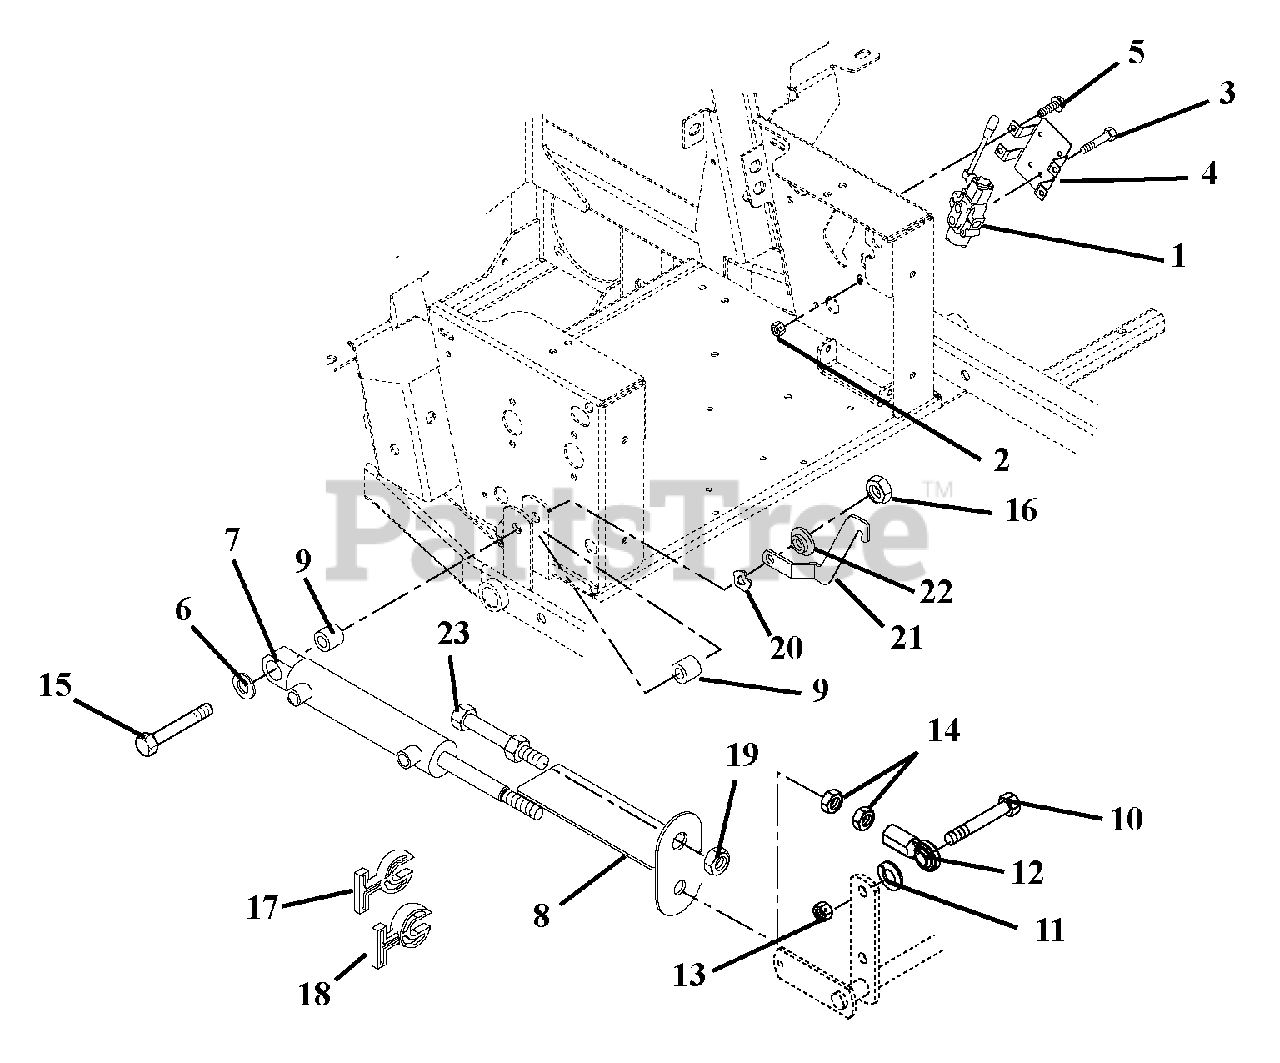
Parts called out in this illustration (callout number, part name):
1	Valve, Hydraulic
2	Nut, Locking Top Flange .31-18
3	Bolt, Hex .31-18 x 2.50 Grade 5
4	Bracket, Valve Mounting
5	Screw-Tapping .38-16 x .50 Hex Washer Head
6	Washer-Flat-Steel .515 x 1.625 x .25
7	Cylinder-Lift
8	Strap-Height of Cut Indicator
9	Bushing .516 x 1.00 x 1.05
10	Bolt-Hex .62-11 x 2.25 Grade 8
11	Washer-Lock .62 x .156
12	Rod End-Right Hand-Female .625
13	Nut-Locking-Center .62-11
14	Nut-Jam .625-18
15	Bolt-Hex .50-13 x 3.75 Grade 5
16	Nut, Locking Top Flange .50-13
17	Stop, Cylinder .34 Thick
18	Stop, Cylinder .68 Thick
19	Nut, Jam .75-16
20	Washer, Wave .076 x 1.12 x .08
21	Latch, Floor Board
22	Bushing-Flange .515 x .75 x .275 x 1.12
